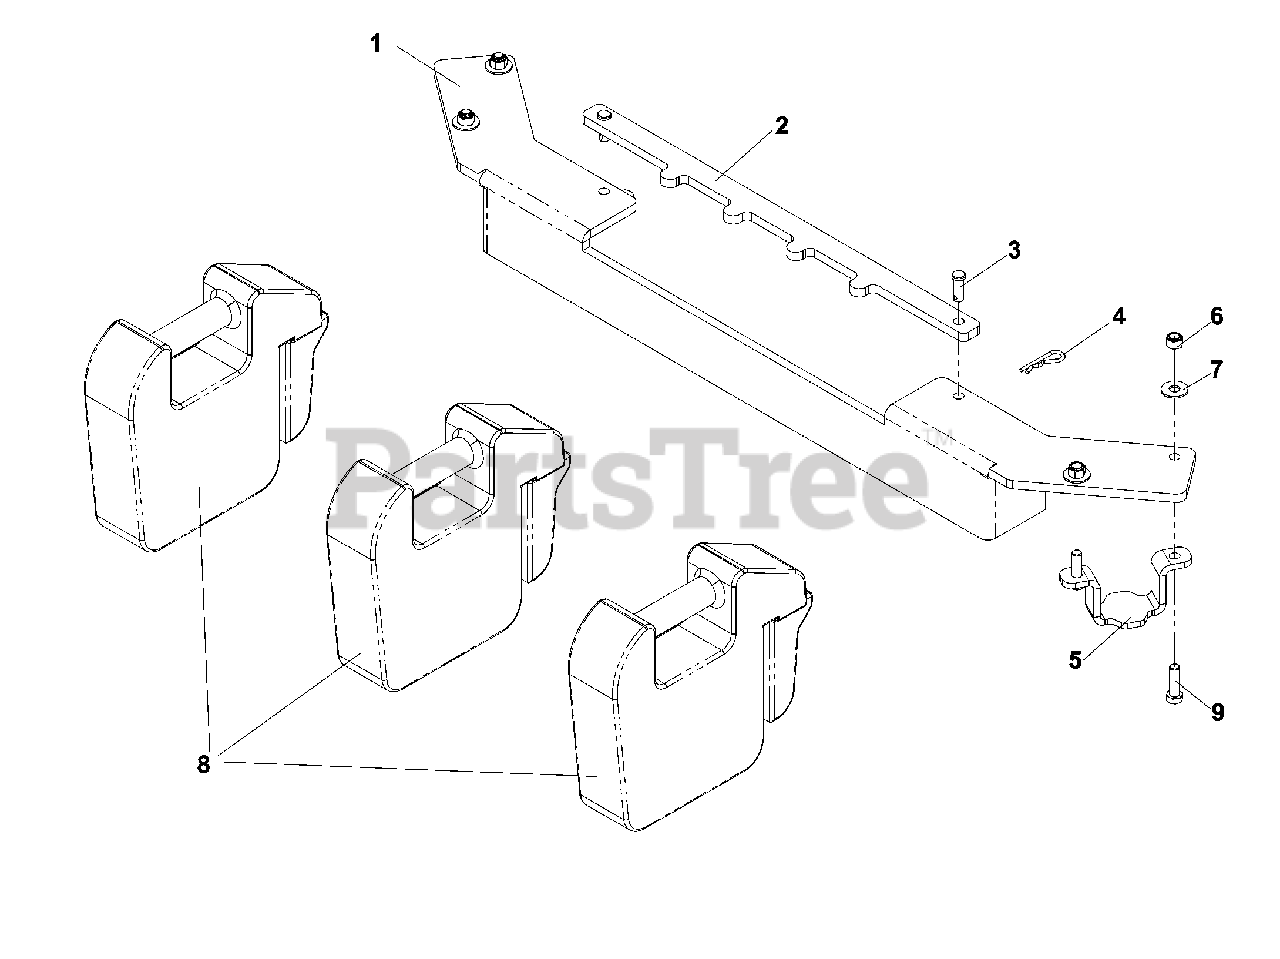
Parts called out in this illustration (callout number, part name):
1	FRONT WT BAR, BLACK
2	HOLD DOWN, WEIGHT BAR
3	CLEVIS PIN
4	RETAINER SPRING
5	WEIGHT KEEPER
6	NUT 3/8-16 NYLOC
7	WASHER 3/8 FLAT
8	FRT WEIGHT CAST PZ DFS
9	HCS 3/8C X 1 1/4 GR5
